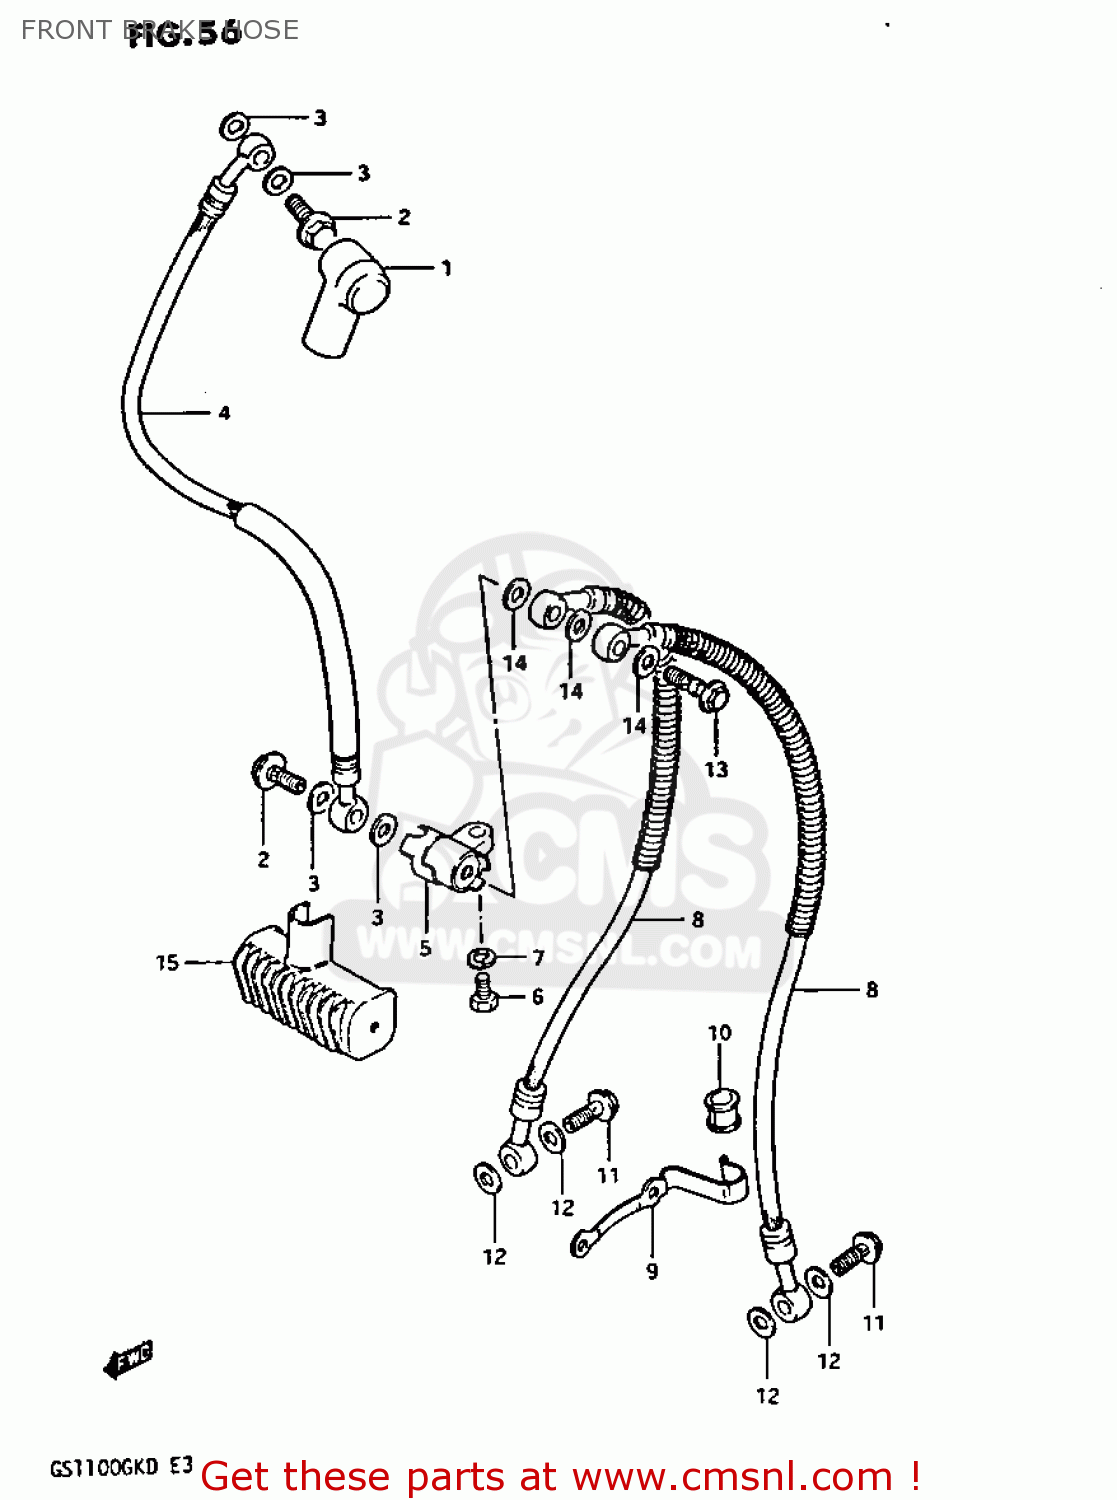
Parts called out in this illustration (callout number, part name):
1	BOOT,MASTER CYLINDER
2	BOLT,UNION
3	WASHER(10X15X1.5)
4	HOSE,FRONT BRAKE
5	JOINT,BRAKE HOSE
6	BOLT
7	WASHER,LOCK
8	HOSE,BRAKE
9	GUIDE,BRAKE HOSE NO.2
10	BUSH,BRAKE HOSE GUIDE,NO.2
11	BOLT,UNION
12	WASHER(10X15X1.5)
13	BOLT,UNION
14	WASHER(10X15X1.5)
15	COVER,BRAKE HOSE JOINT
